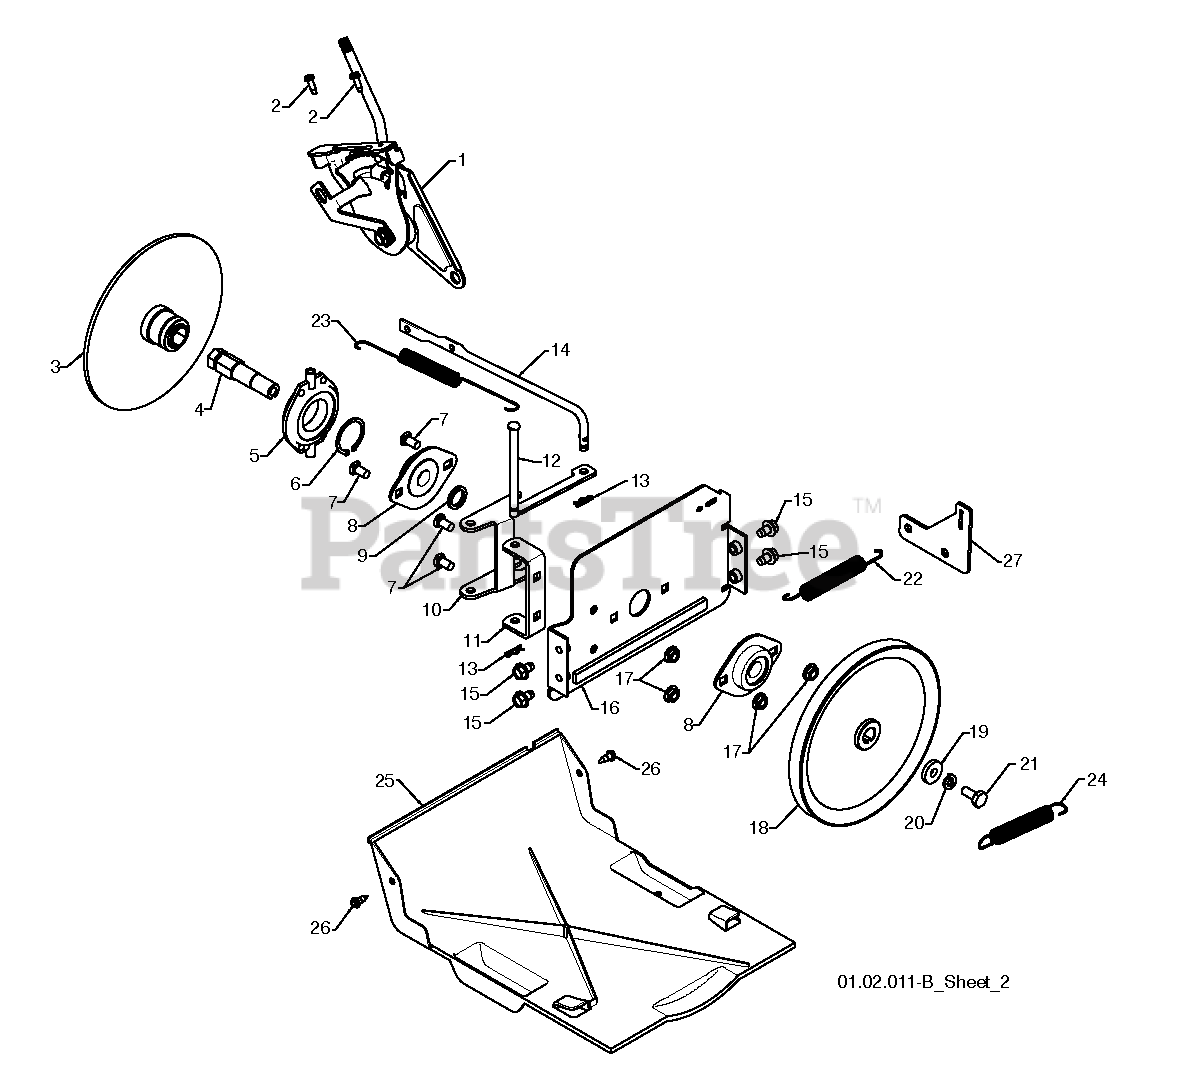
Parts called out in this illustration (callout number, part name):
1	HEAD ASSY SPEED
2	SCREW #10-24 X 5/8
3	DRIVE PLATE WELDMENT
4	SHAFT.HEX.SHORT
5	TRUNNION BEARING ASSY
6	RETAINING RING
7	BOLT
8	BEARING FLANGE
9	SPACER, BEARING
10	LEVER.SHIFTER.PLATE.BLACK
11	BRACKET.SHIFTER.SUPPORT.BLACK
12	PIN, PIVOT LEVER
13	RETAINER CLIP PM
14	ROD.CLUTCH.YELLOW.ZINC(VT)
15	SCREW LT
16	PLATE.DRIVE.MOUNT.BLACK
17	NUT.FLANGE.5/16
18	PULLEY.TRACTION.7.75
20	LOCKWASHER
22	SPRING.TRACTION.IDLER
23	SPRING.RETURN
24	SPRING, BRAKE
25	PAN.BOTTOM.PLASTIC
26	SCREW, HEX HEAD, TAPPING
27	BRACKET.TRACTION.SPRIN
